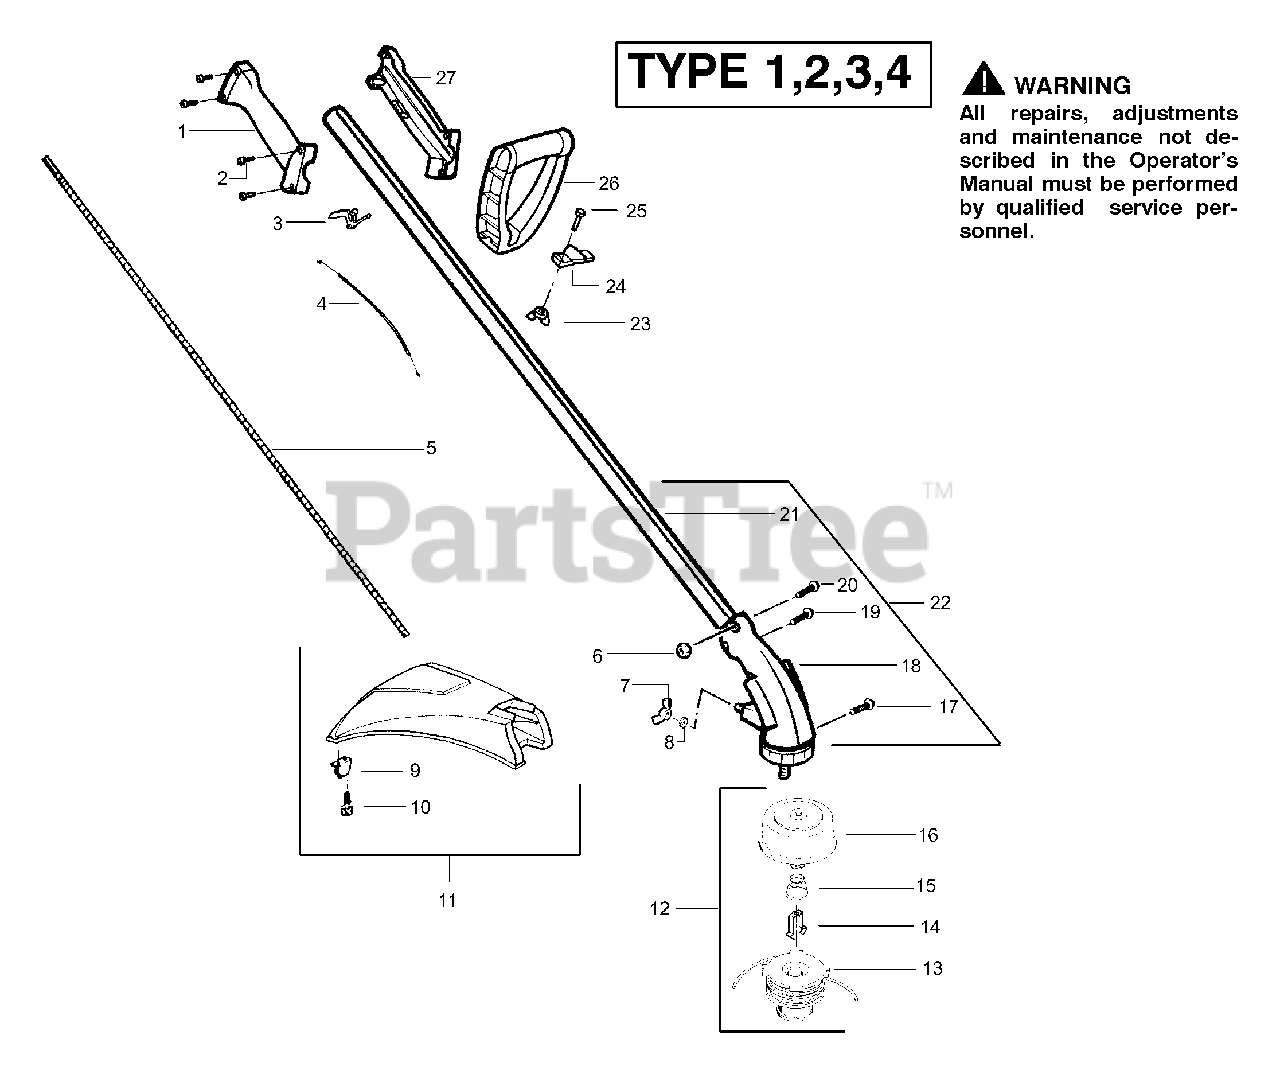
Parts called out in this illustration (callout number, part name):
1	Throttle Hsg. (Right)
2	Screw-Throttle Hsg.
4	Assy-Throttle Cable
5	Flex-Drive Shaft
6	Locknut-Gear Box
7	Wingnut-Gear Box
9	Line Limiter
10	Screw-Line Limiter
11	Kit-Shield Ass'y.
12	Accy-Cutting Head Ass'y.
13	Accy-Spool w/Line
14	Clip-Retainer
16	Kit-Hub Ass'y
18	Assy-Gear Box
21	Assy-Drive Shaft Hsg.
22	Kit-Gearbox/Shaft
23	Wingnut Handle
24	Clamp Handle
25	Bolt Handle
26	Assist Handle
27	Throttle Hsg. (Left)
